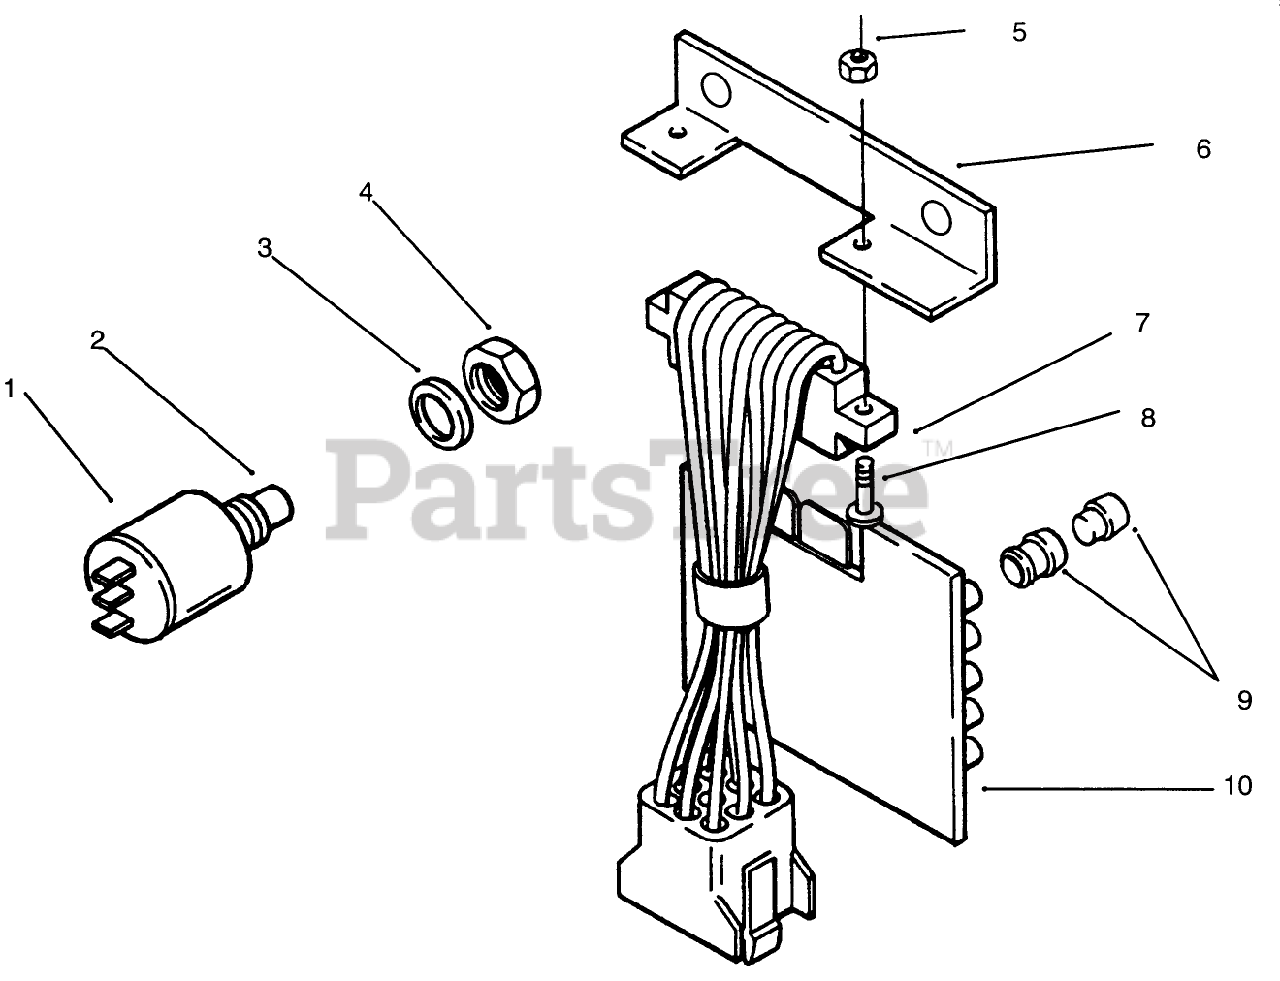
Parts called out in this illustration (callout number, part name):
1	SWITCH-PUSH BUTTON
4	NUT F/W 116796
5	NUT-HEX, NYL INS
6	BRACKET
7	P.C. BOARD HARNESS
8	Screw
9	ASSY LENS & BUSHING
